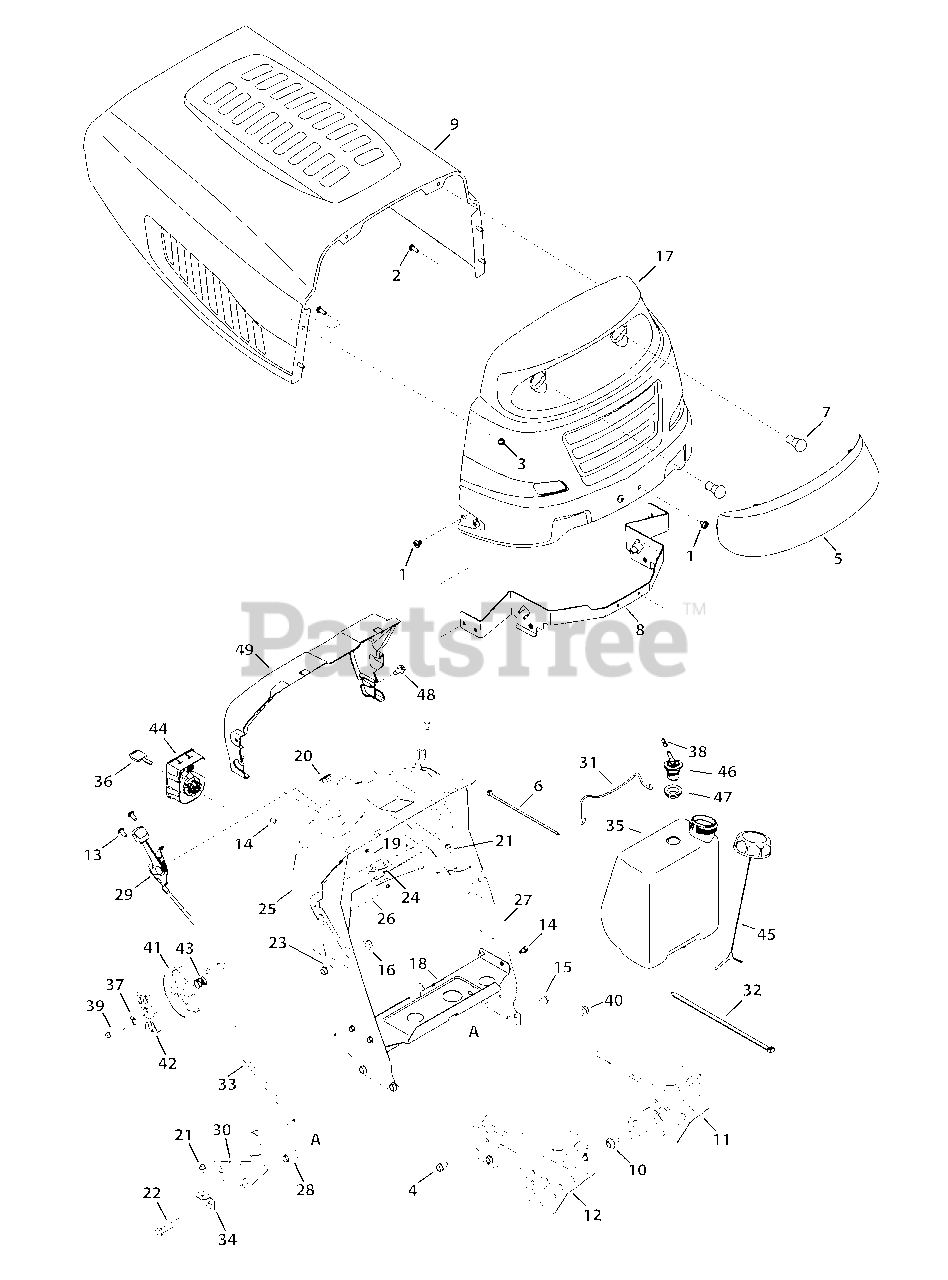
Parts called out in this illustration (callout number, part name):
1	Screw, 5/16-18 x .375
2	Hex Screw, 1/4-20 x .620
3	Flangelock Nut, 1/4-20
4	Screw, 5/16-18 x .750
5	Grill Lens
6	Cable Tie
8	Hood Pivot Bracket
10	Shoulder Screw, 5/16-18 x .43 x .29
11	Left Support Pivot Bracket
12	Right Support Pivot Bracket
13	Screw, 1/4-20 x .500
14	Screw, 1/4-20 x .500
15	Screw, 5/16-18 x .625
16	Flangelock Nut, 5/16-18
17	Grill
18	Gas Tank Support Bracket
19	Screw, #10-16 x .500
20	Choke Plug
21	Tap Screw, 1/4-20, 0.625
22	Hex Screw, 3/8-16 x 2.0
23	Hex Screw, 5/16-18 x .625
24	Bearing, .628 ID x 1.36
25	Dash, Upper NRMC
27	Dash, Lower
28	Flange Spacer, .390 x .671 x 1.095
29	Throttle/Choke Cable
30	Speed Latch - No RMC
31	Battery Assembly Rod
32	Cable Tie
33	Speed Control Rod
34	Speed Latch Tab
35	1.36 Gallon Fuel Tank
36	Key, Assembly
37	Lock Washer, 1/4
38	Hose Vent, 3/16 EPA
39	Hex Washer Screw, 1/4-20 x 1.50
40	Flangelock Nut, 3/8-16
41	Shift Lever
42	Index Control
43	Compr. Spring, .72 OD x .78
44	3 Position Key Switch
45	Fuel Cap, 2.25"
46	Rollover Valve
47	Rubber Grommet, 23 x 3.55
48	Screw, 1/4-15 x .750
49	Dash Collar
